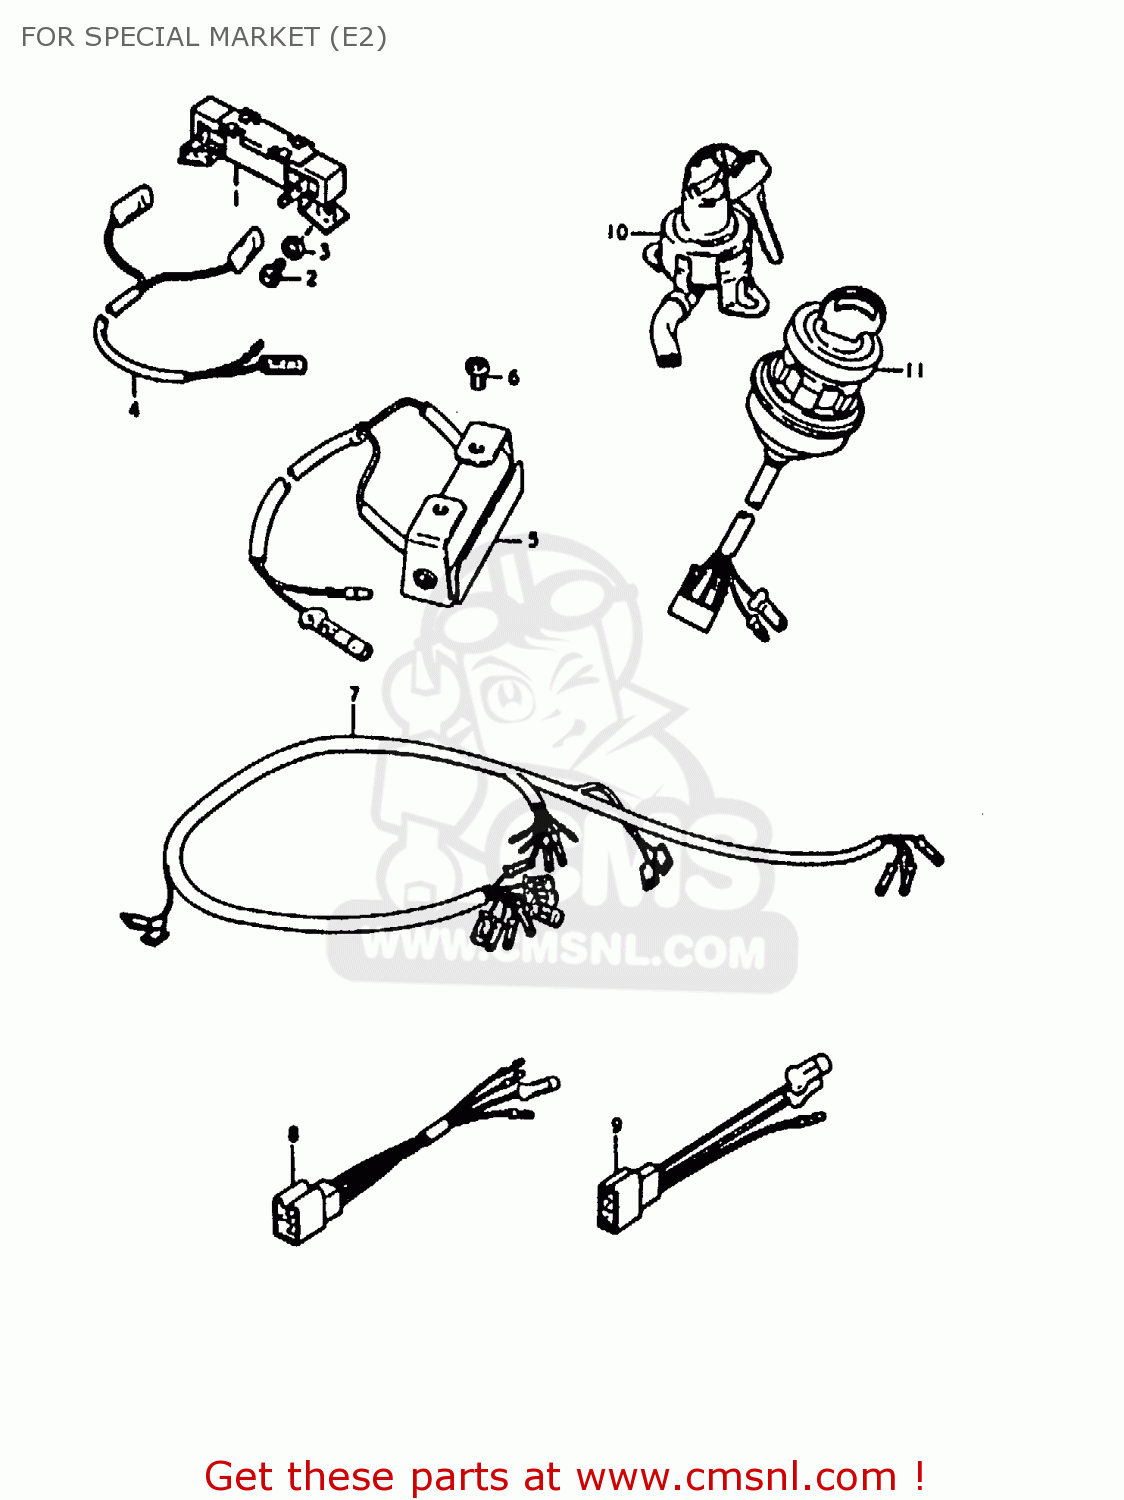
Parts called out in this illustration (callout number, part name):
1	RESISTOR, MAGNETO
2	BOLT 5X16
3	WASHER 5MM
4	LEAD WIRE, RESISTOR
5	RESISTOR, MAGNETO
6	SCREW
7	WIRING HARNESWS
8	WIRE
9	WIRE,HEADLAMP GROUND
10	SWITCH ASSY, IGNITION
11	SWITCH ASSY, IGNITION
